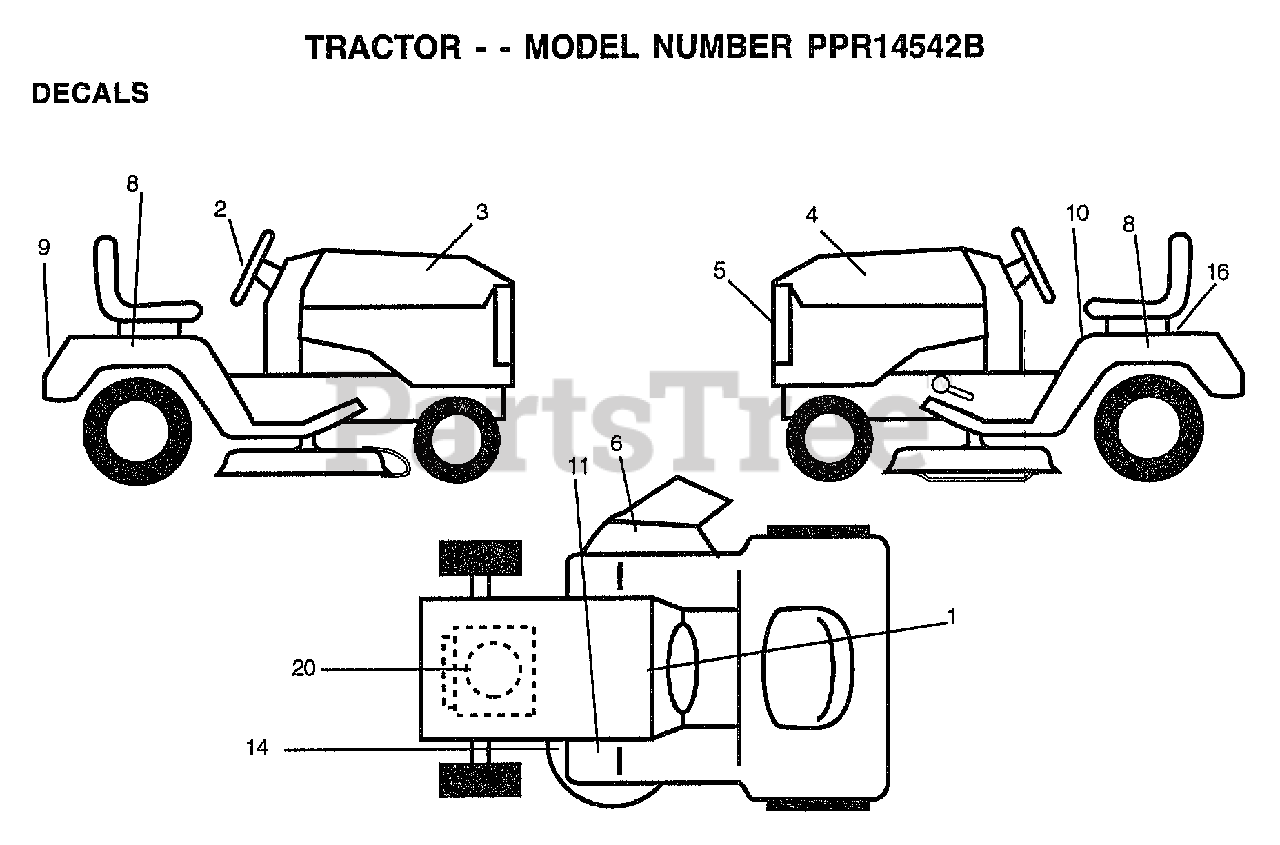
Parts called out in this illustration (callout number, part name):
1	"DECAL.OPER,SDL"
2	"DECAL WHEEL,STEER"
3	"DECAL-HOOD,RH"
4	"DECAL-HOOD,LH"
5	DECAL.GRILLE/LENS
6	"DECAL, WARNING"
8	DECAL.FENDER.SD.LAWN
9	"DECAL FENDER,LOGO"
10	DECAL.CAUT.ENG/FR
11	DECAL T
14	"DECAL-SCHEM,BELT"
16	DECAL.BATRY.3-3908
20	DECAL HP ENGINE
